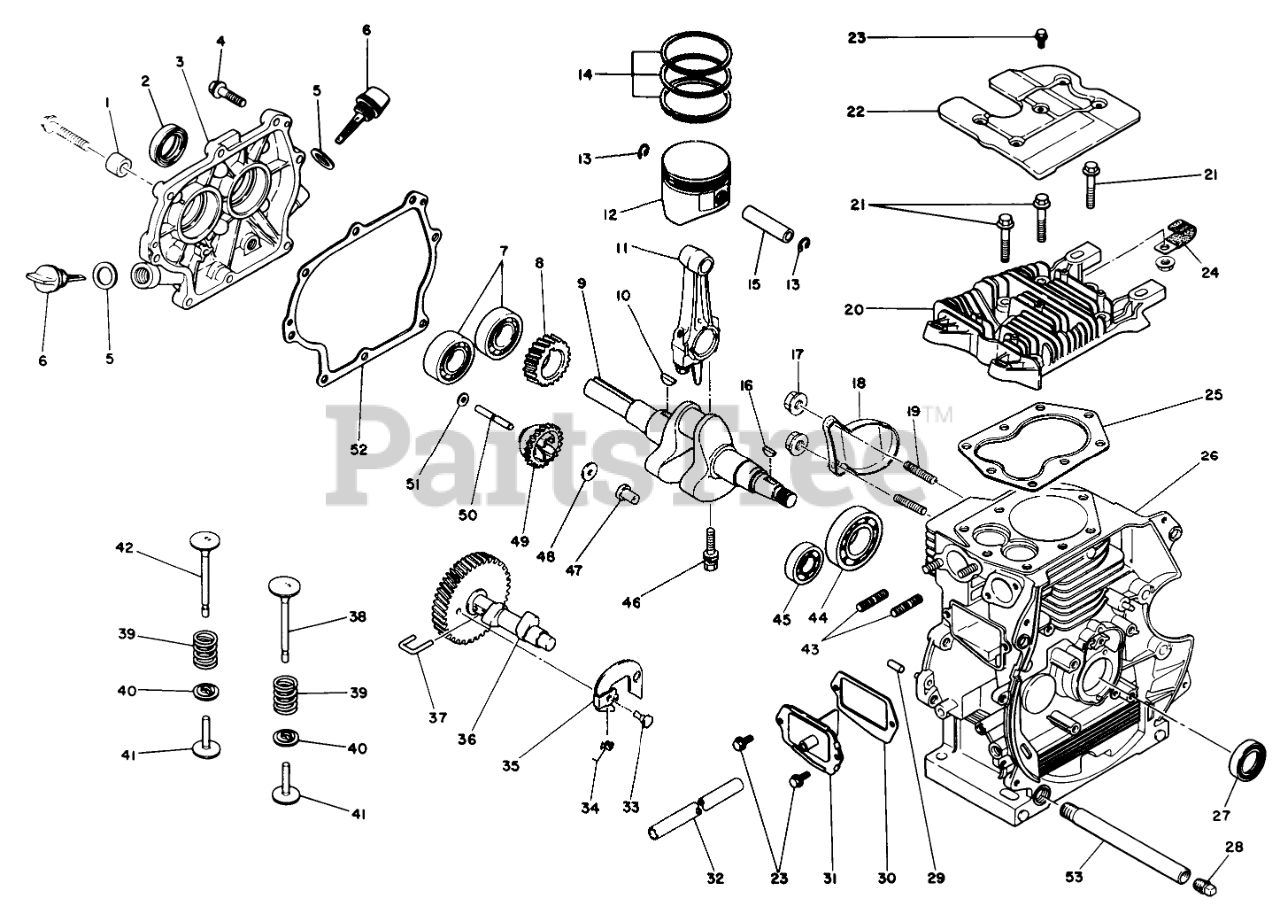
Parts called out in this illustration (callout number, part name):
1	SPACER
2	OIL SEAL
3	COVER-CRANKCASE
5	GASKET
6	Gauge-Oil (Incl. Ref. #5)
7	BEARING
8	CRANKSHAFT GEAR
9	CRANKSHAFT
11	Connecting Rod Assembly (Std.) (Incl. Ref #46)
12	Piston Assembly (Std.) (Incl. Ref. #15)
14	PISTON RING SET
15	PIN - PISTON
18	COVER
20	CYLINDER HEAD
22	COVER-HEAD
24	CLAMP
25	HEAD GASKET
26	Cylinder Block Assembly (Incl. Ref. #19, 29 & 43)
27	OIL SEAL
28	CAP-PIPE
30	GASKET=BRTHR
31	BREATHER VALVE ASM
32	BREATHER TUBE
34	SPRING
35	FLYWEIGHT
36	Camshaft Assembly (Incl. Ref. #33-35 & 37)
38	INTAKE VALVE
39	VALVE SPRING
40	RETAINER VALVE
41	TAPPET
42	EXHAUST VALVE
44	BEARING
45	BEARING
46	CONNECTING ROD BOLT
47	SLIDER-GOV
48	SPACER
49	Governor Gear Assembly (Incl. Ref. #47)
50	SHAFT-GOV.
51	WASHER
52	GASKET
53	DRAIN TUBE
